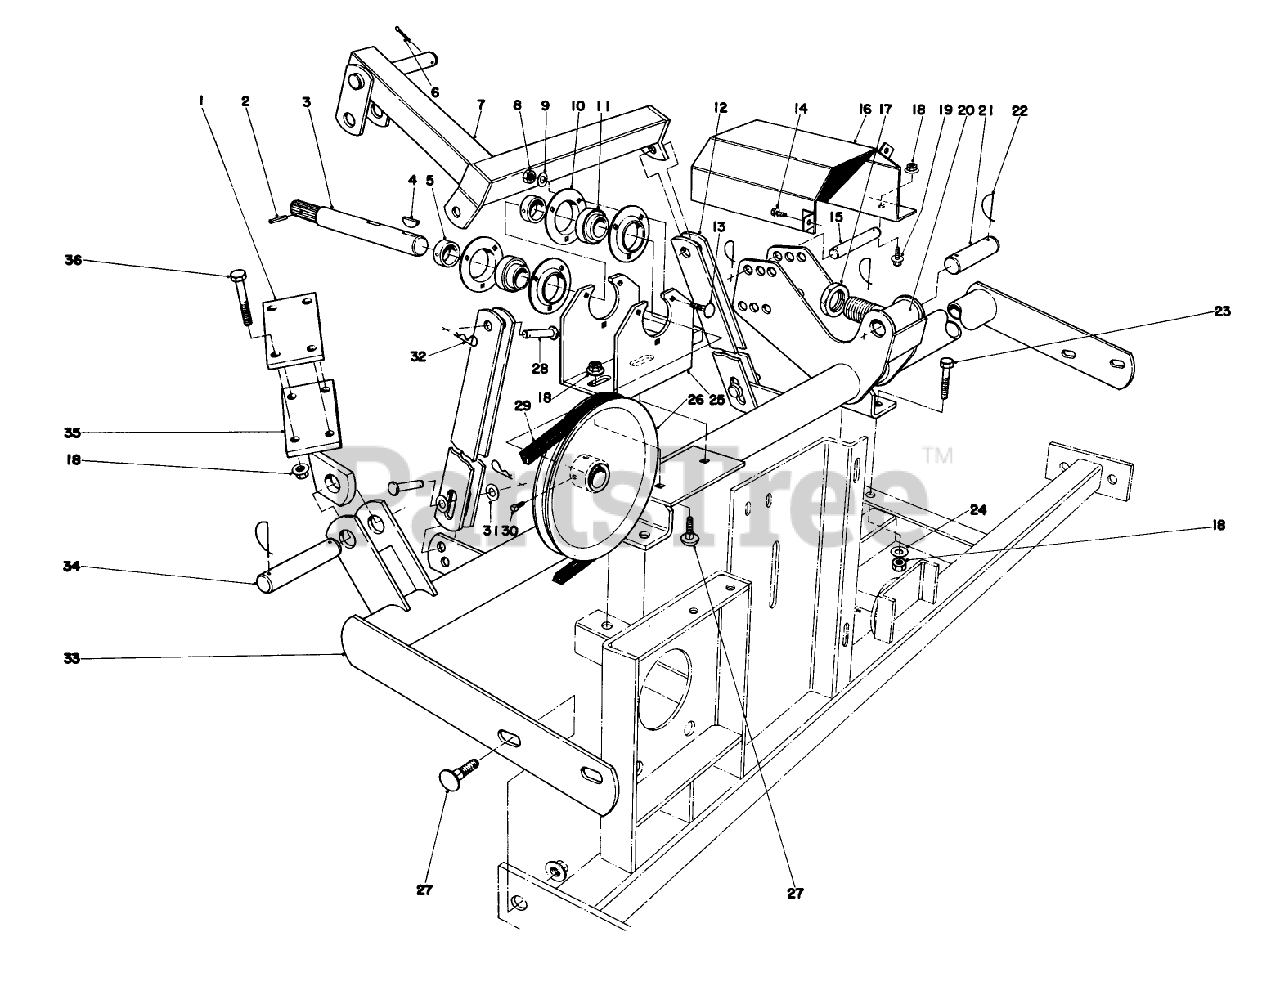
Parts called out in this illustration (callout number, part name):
1	Clamp Plate
2	PIN-ROLL, SLOTTED
3	JACKSHAFT
4	KEY-WOODRUFF
5	COLLAR-LOCK, BEARING
6	PIN-COTTER
7	LIFT ARM WA
8	NUT-HEX
9	WASHER-LOCK/SP
10	FLANGE
11	Bearing (Incl. Ref. #5)
12	LIFT STRAP
13	BOLT-CARR
14	SCREW-HHF
16	Power Take Off Shield
17	NUT-HJ
18	NUT-HHF, WHIZ
19	SCREW-HHF
20	Push Pin
21	PIN-PLAIN
22	PIN-LYNCH
23	SCREW-HH
24	WASHER-FLAT
25	JACKSHAFT SUPPORT
26	PULLEY 9 IN OD
27	BOLT-CARR
28	PIN-CLEVIS
29	V BELT
30	SCREW-SQH
31	WASHER-FLAT
32	PIN-COTTER, HAIR
33	Hitch Adapter
34	Pin
35	Push Arm Bracket
36	SCREW-HH
